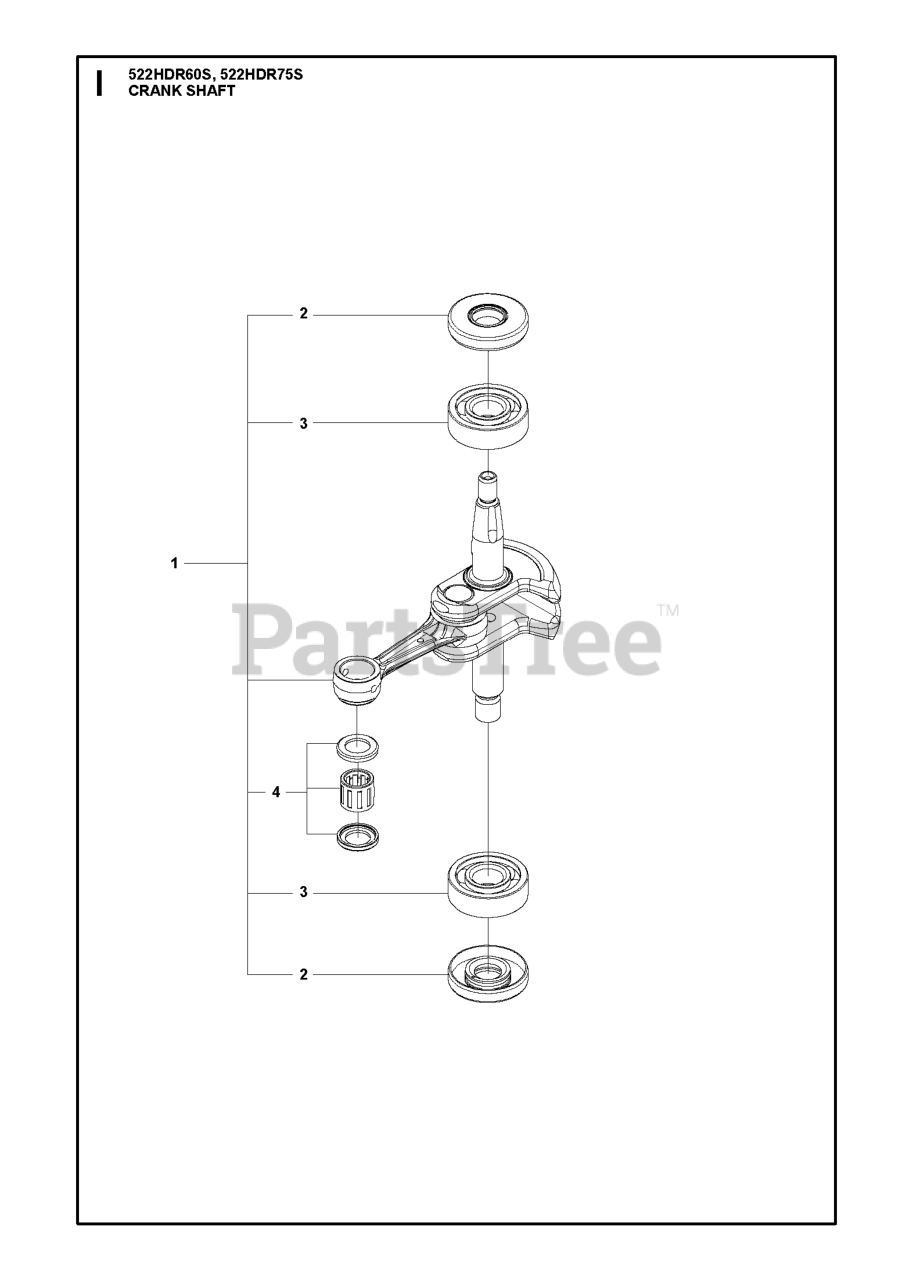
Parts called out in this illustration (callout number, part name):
1	CRANKSHAFT KIT
2	SEALING RING
3	BALL BEARING
4	BEARING KIT PISTON PIN
